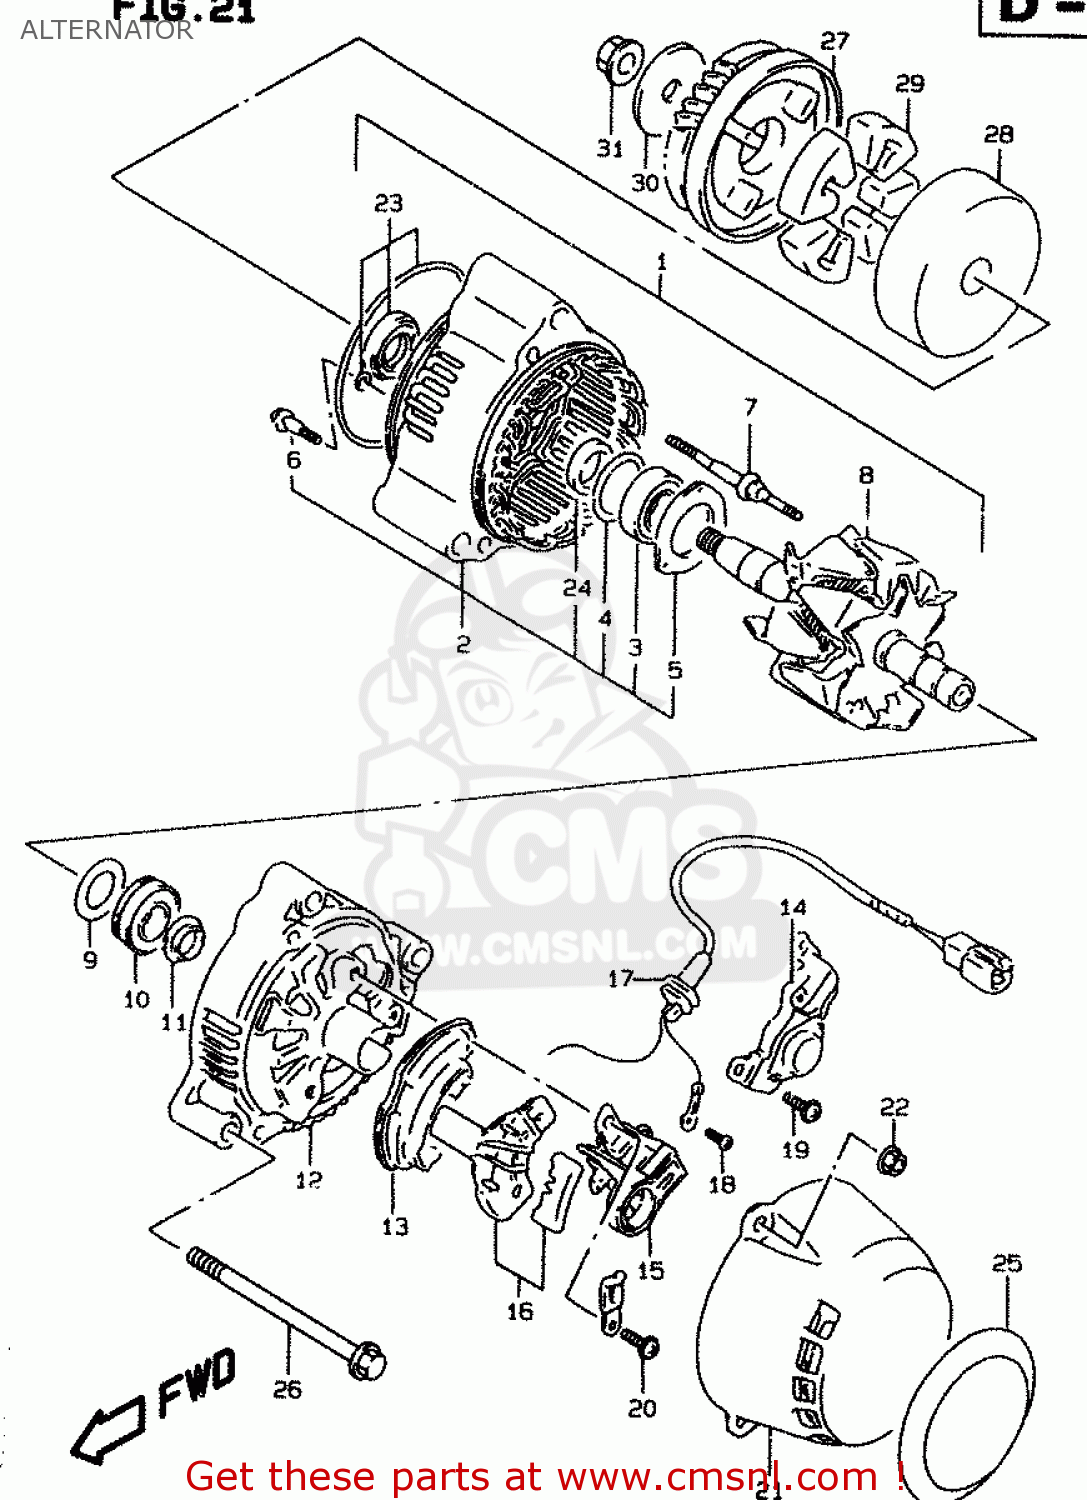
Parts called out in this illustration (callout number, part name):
1	ALTERNATOR ASSY
2	FRAME,DRIVE END
3	BEARING
4	COVER,BEARING
5	RETAINER
6	SCREW,BEARING RETAINER
7	STUD BOLT
8	ROTOR ASSY
9	COVER,BEARING
10	BEARING
11	COVER(2)
12	FRAME,END
13	HOLDER,RECTIFIER
14	REGULATOR
15	HOLDER,BRUSH
16	COVER,RECTIFIER
17	WIRE,LEAD
18	SCREW 4X6
19	SCREW
20	SCREW
21	COVER
22	NUT
23	SERVICE KIT(A)
24	SPACER
25	PLATE,ALTERNATOR ABSORBER
26	BOLT
27	GEAR,GENERATOR DRIVEN
28	HOUSING,GENERATOR GEAR DAMPER
29	DAMPER,GENERATOR DRIVEN
30	WASHER
31	NUT
